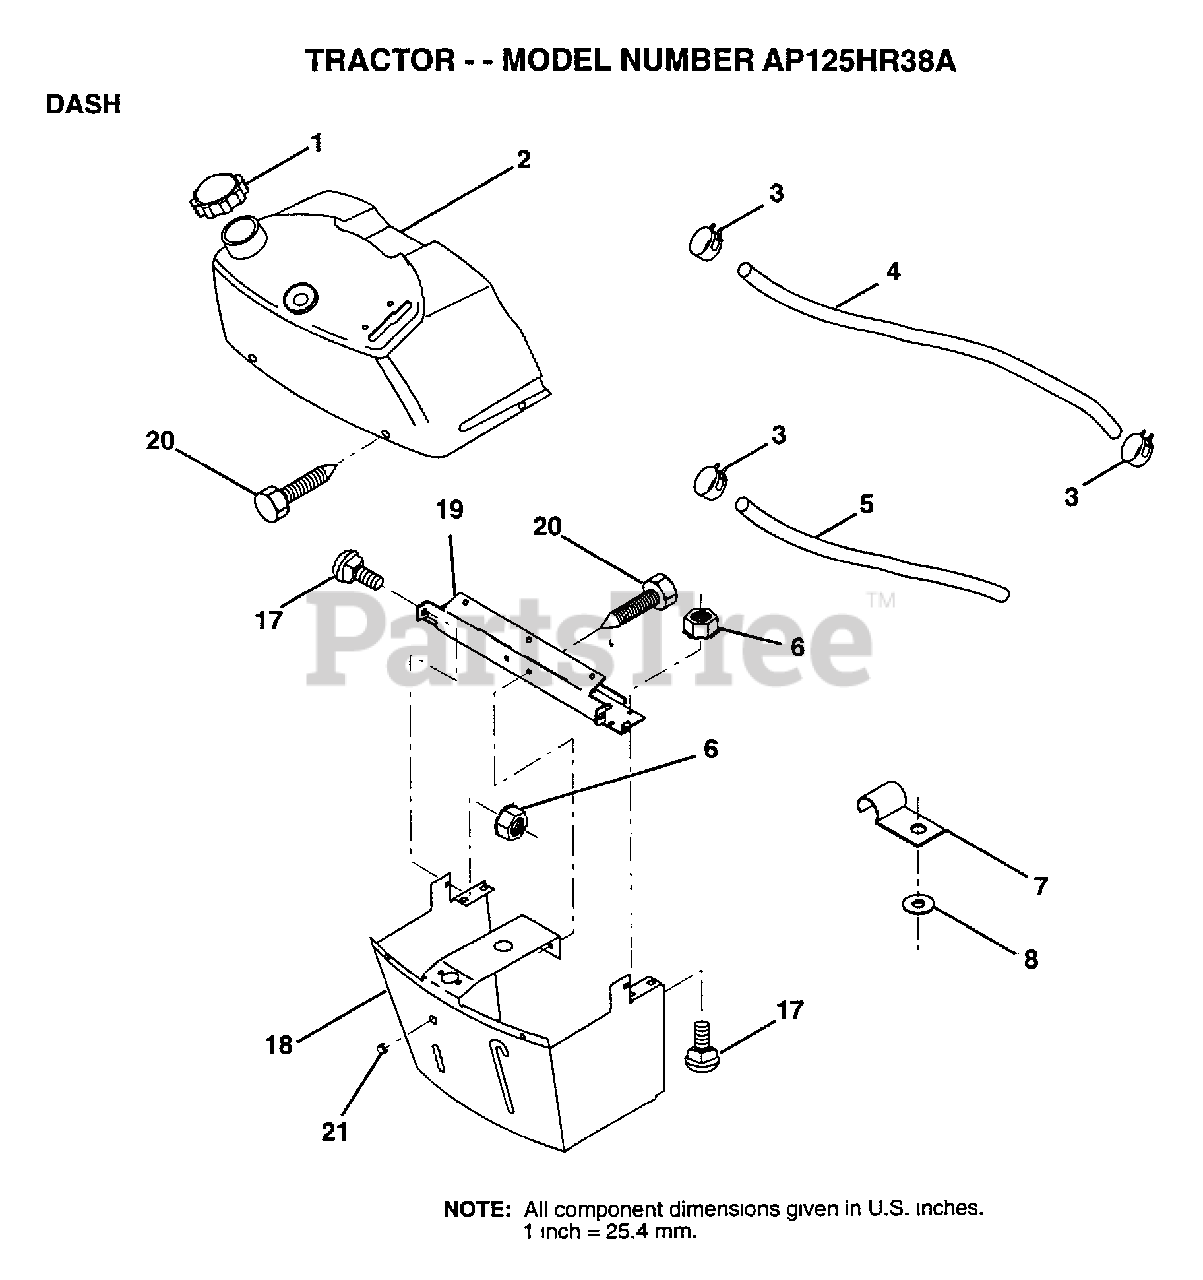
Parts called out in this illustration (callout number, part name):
1	CAP BLK FUEL LR
2	TANK.ASM.DASH.LR
3	HOSE CLAMP
5	FUEL LINE T
6	NUT HXKEP 1/4X20
7	CLIP T
8	WASHER PM
17	BOLT
18	SUPT ASM DASH
19	CROSS BRACE
20	SCREW.1/4-20X1/2
21	PLUG DOME
